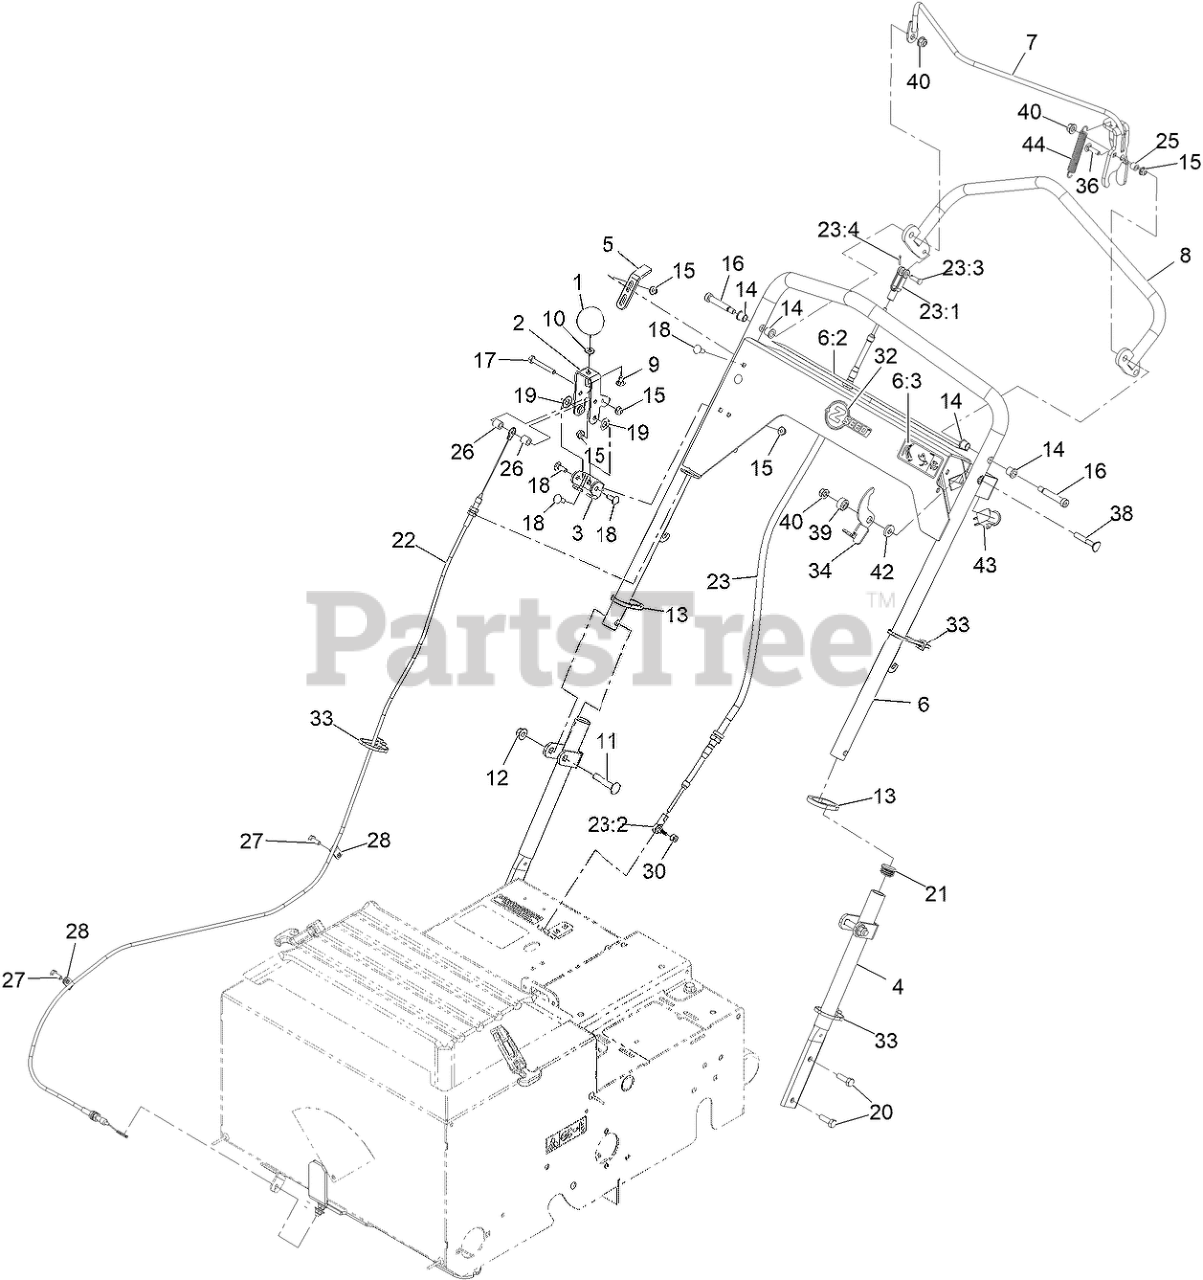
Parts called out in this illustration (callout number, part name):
1	KNOB-RATE, FLOW
2	LEVER-ADJUST, FLOW
3	BRACKET-ADJUST, FLOW
4	HANDLE-LOWER
5	BRACKET-ADJUST, DRIVE
6:2	DECAL-CONTROL PANEL, SEED
6:3	DECAL-SAFETY LATCH
7	BAIL-CLUTCH
8	DRIVE HANDLE WA
9	SCREW-CARR
10	WASHER-FLAT
11	SCREW-CARR
12	NUT-HF, NI
13	RING-HANDLE LOCK
14	BEARING
16	SCREW-SHOULDER
17	SCREW-HH
18	BOLT-CARR
19	WASHER-PLAIN
20	SCREW-HH
22	CABLE-FLOW, SEED
23	CABLE-PUSH PULL
23:2	Ball Joint
23:3	Pin-Clevis
23:4	PIN-COTTER
27	SCREW-HH
28	CLAMP-R
30	NUT-LOCK
32	DECAL-Z-SEED LOGO
33	TIE-CABLE
34	LATCH-BAIL
36	SCREW-CARR
39	BUSHING-STEPPED
40	NUT-HF, NI
42	WASHER-FLAT
43	SWITCH-BAIL
